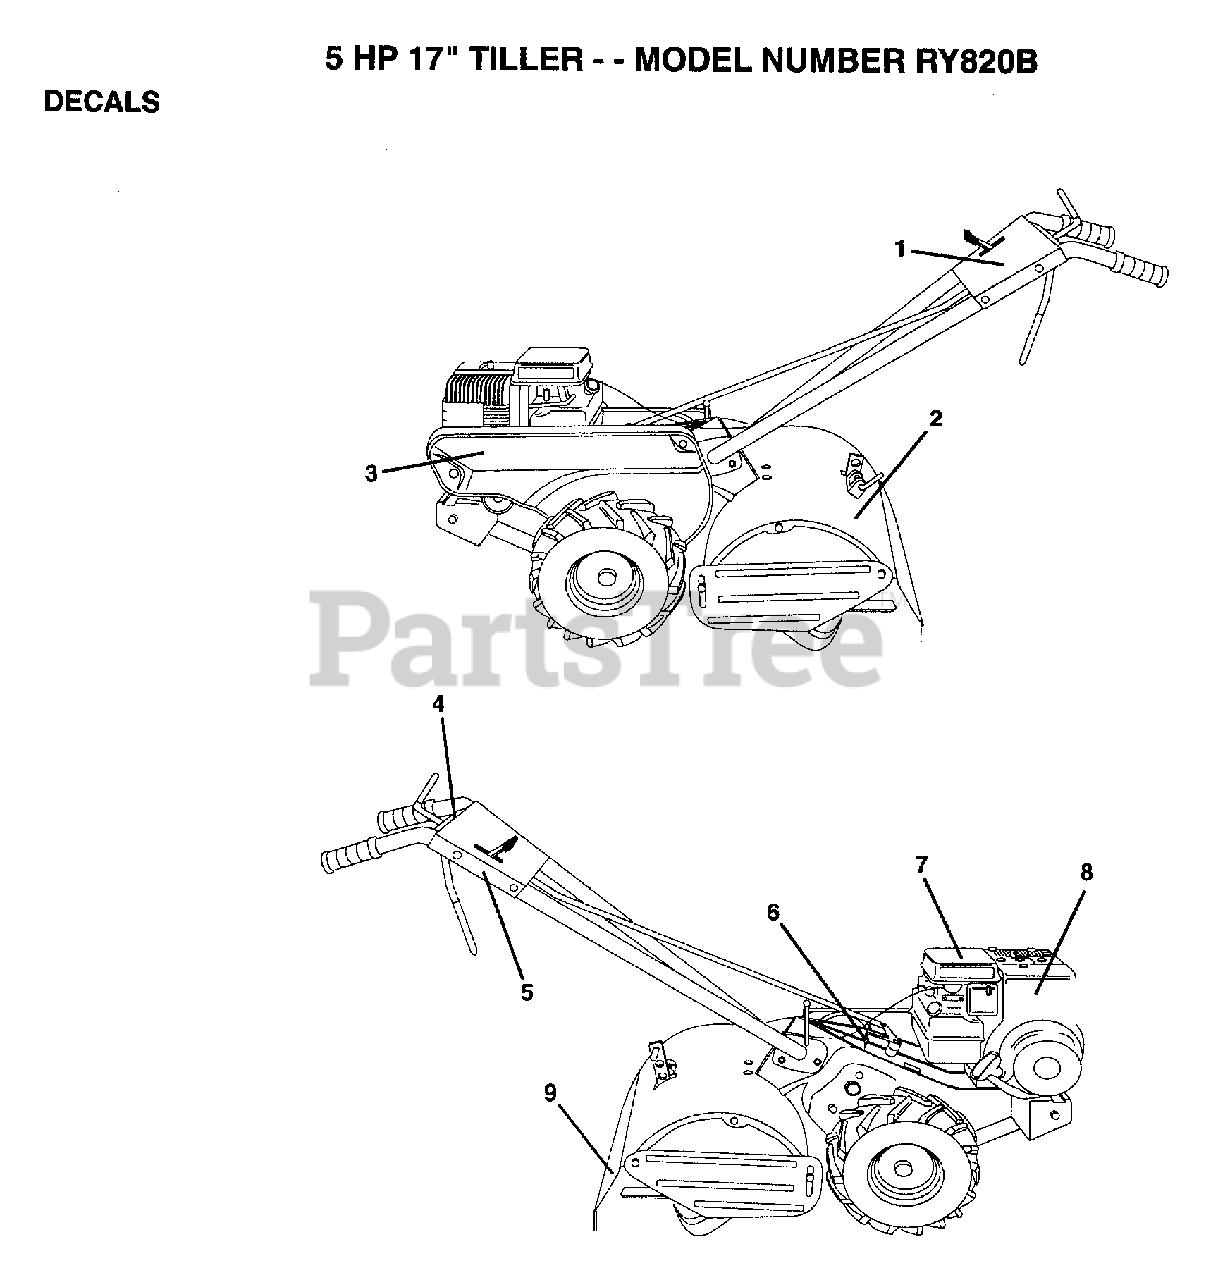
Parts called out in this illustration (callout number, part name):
3	DECAL, LOGO
5	DECAL TI
7	DECAL TI
